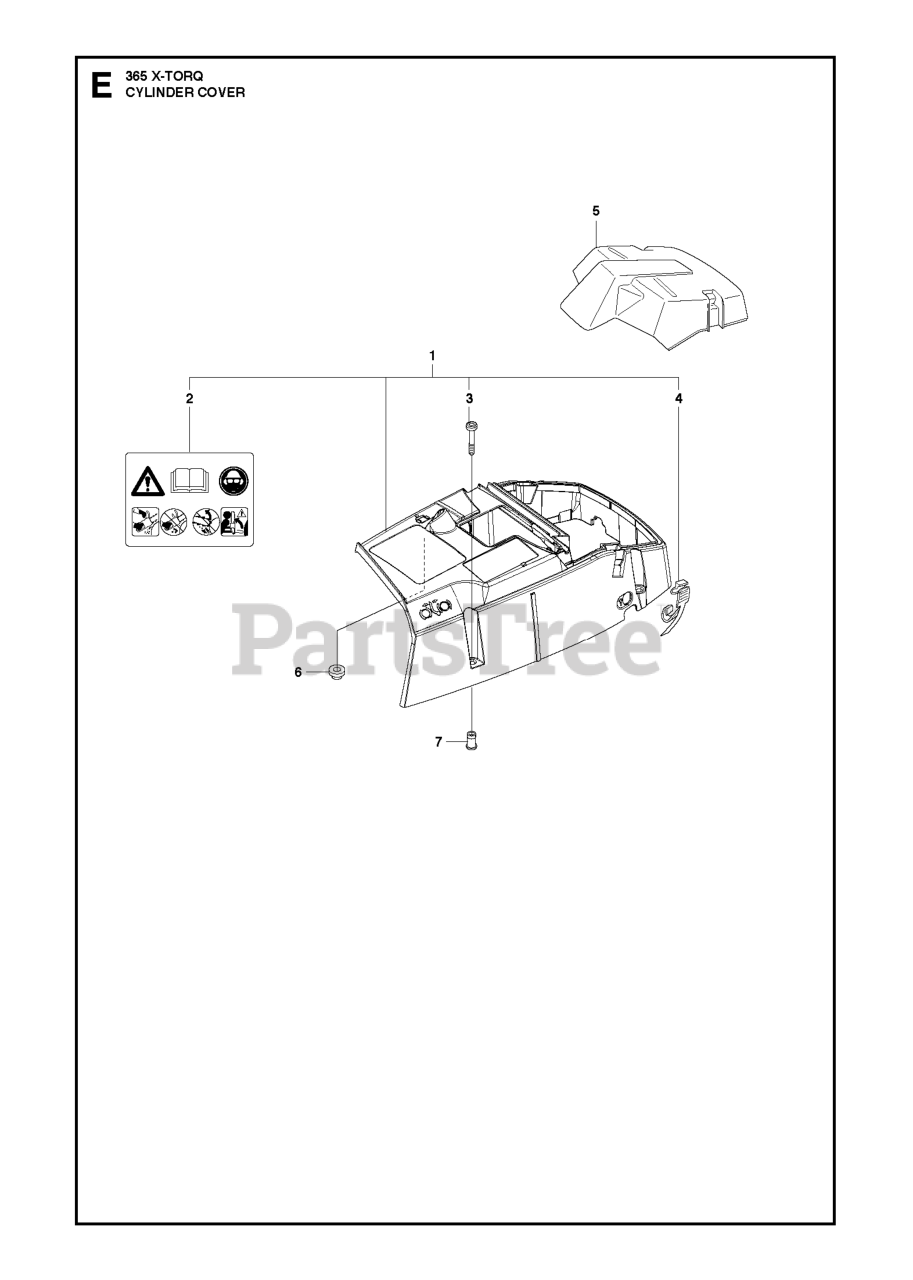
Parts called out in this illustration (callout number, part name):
1	CYLINDER COVER ASSY
3	SCREW CITXPANMO
7	SLEEVE CYLINDER
